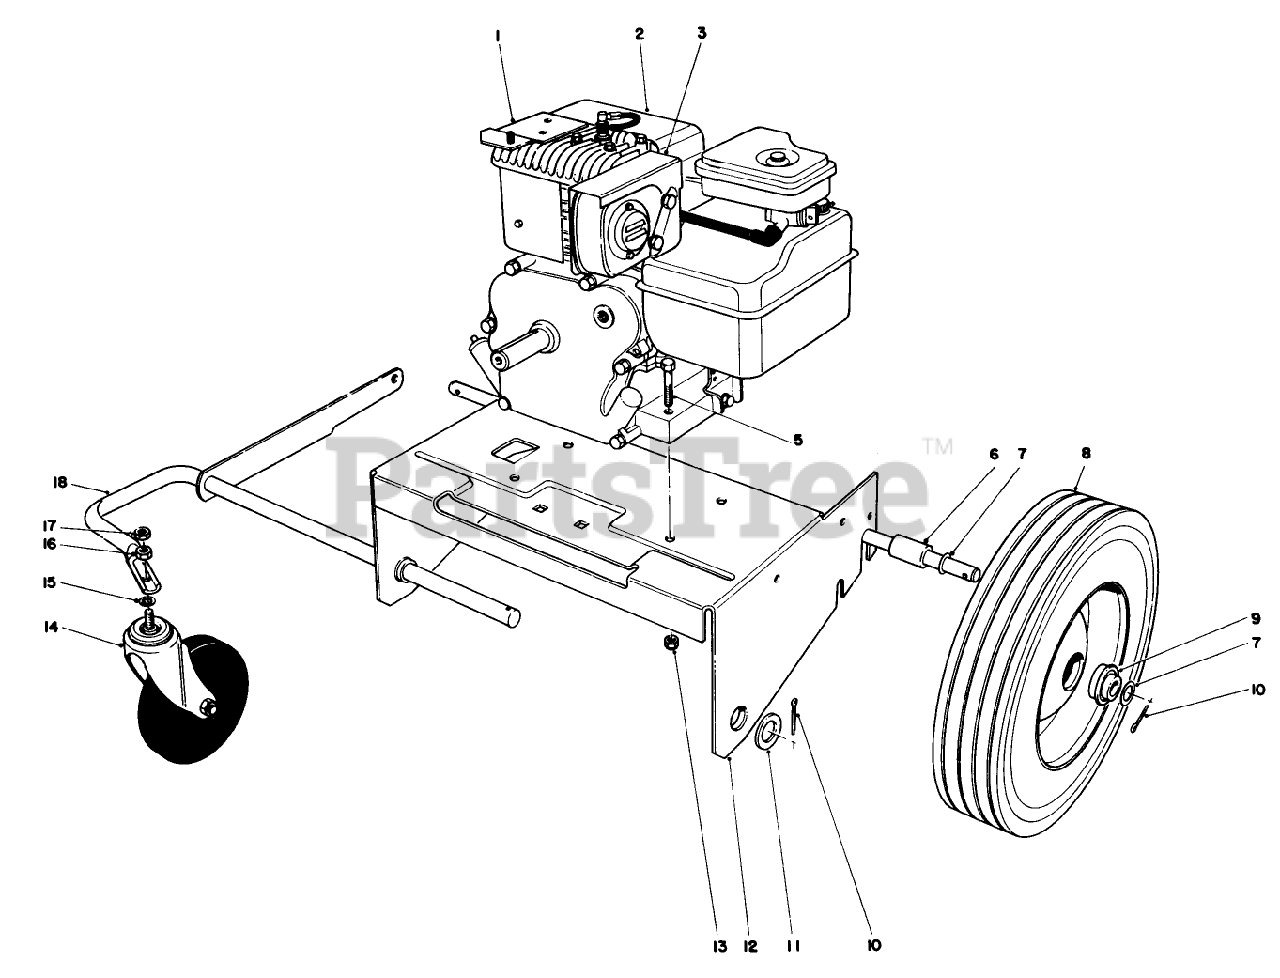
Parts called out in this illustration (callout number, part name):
1	MTG BRKT WA *B
2	ORDER FROM BRIGGS
3	HEAT SHIELD
5	SCREW-HH
6	SPACER-AXLE
7	WASHER
8	WHEEL
9	BEARING
10	PIN-COTTER
11	WASHER-FLAT
13	NUT-LOCK, CONE
14	CASTER
15	WASHER-LOCK/INT
16	NUT-HH
